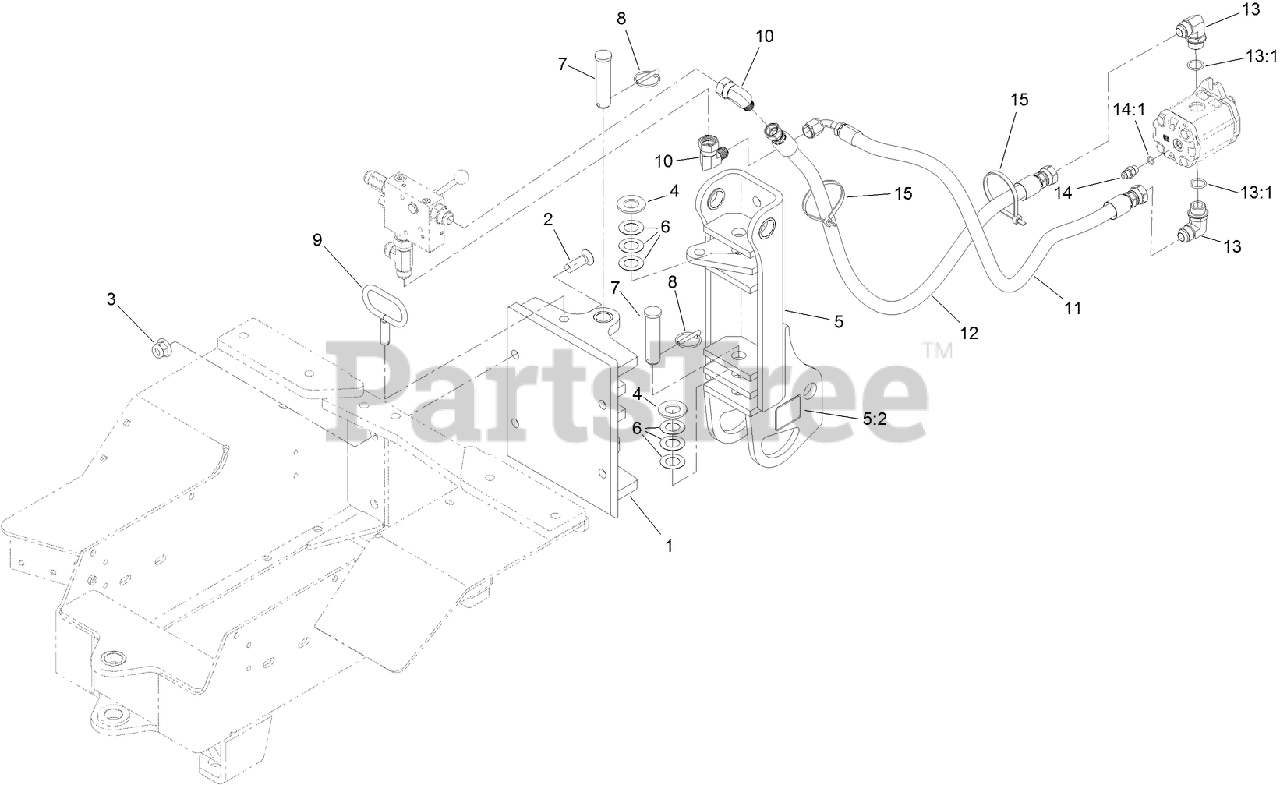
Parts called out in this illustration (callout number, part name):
1	SLIDE-QUICK ATTACH
2	SCREW-HSFH
3	NUT-HHF
4	WASHER-FLAT
5	PIVOT ASM
5:2	DECAL-TIE DOWN
6	WASHER-FLAT
7	PIN-PIVOT
8	PIN-KLIK
9	LOCK-SWING
10	FITTING-ELBOW, 90
11	HOSE ASM
12	HOSE ASM
13	FITTING-ELBOW, 90 DEG
13:1	O-RING
14	FITTING-STRAIGHT
14:1	O-RING
15	TIE-CABLE
